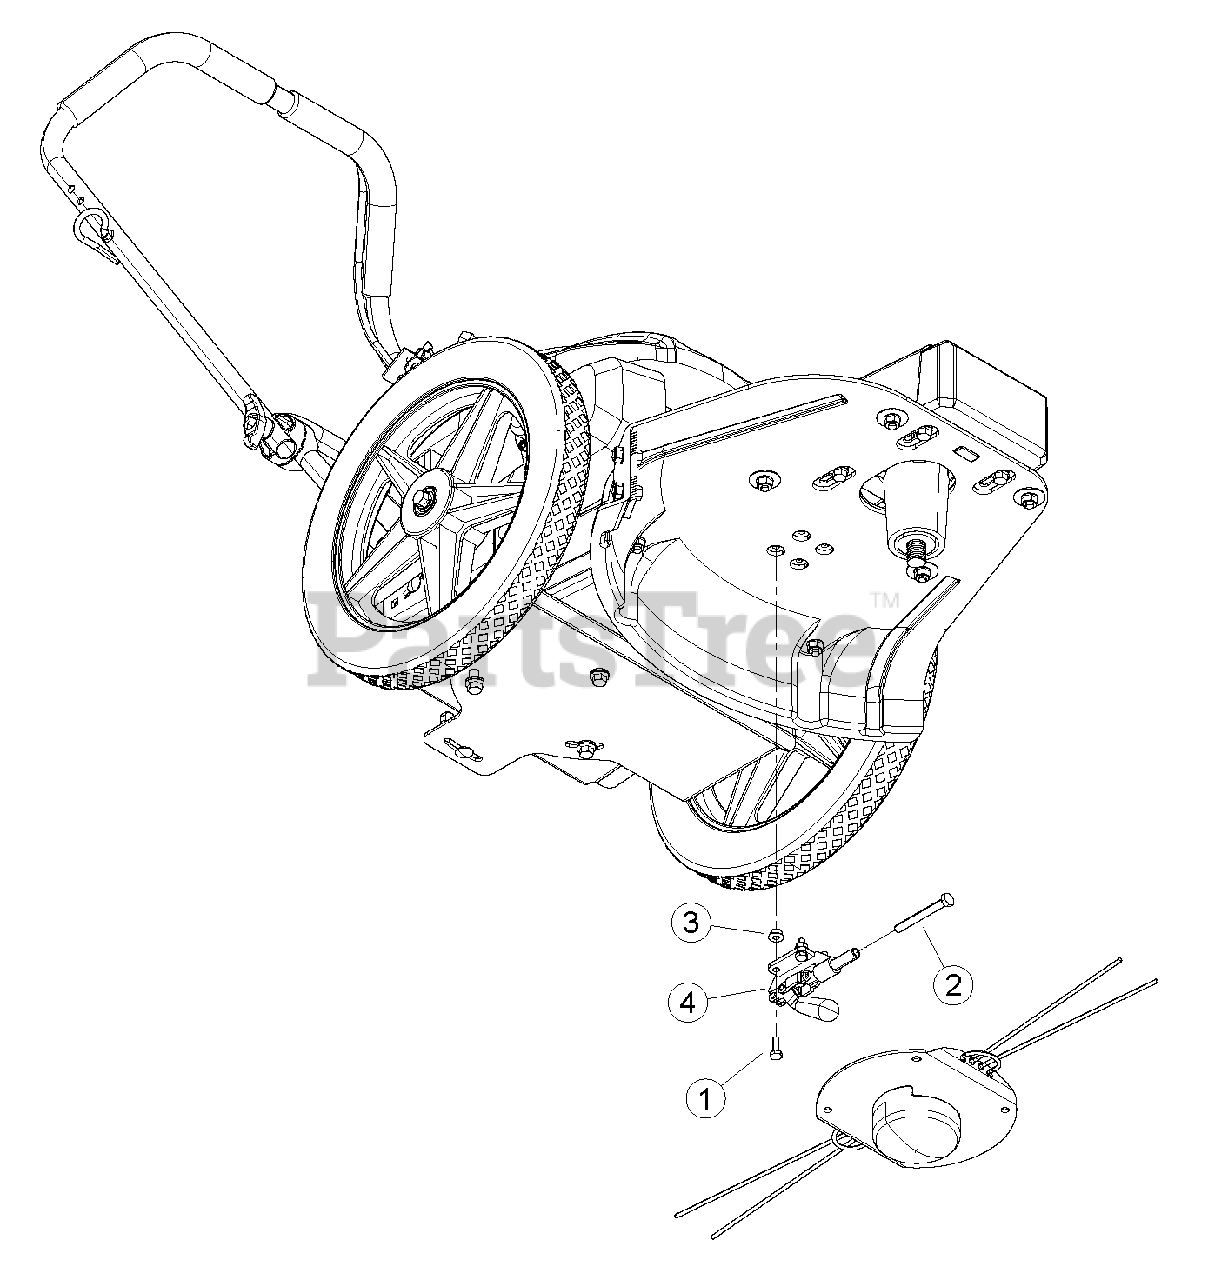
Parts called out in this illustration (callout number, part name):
1	BOLT, 1/4 X 3/4 HEX HD
2	BOLT, 5/16 NCX 2-3/4 GR5 HCPS ZP
3	NUT, 1/4-20 NYLOCK FLANGE
4	CLAMP, STRAIGHTLINE 600 LB
